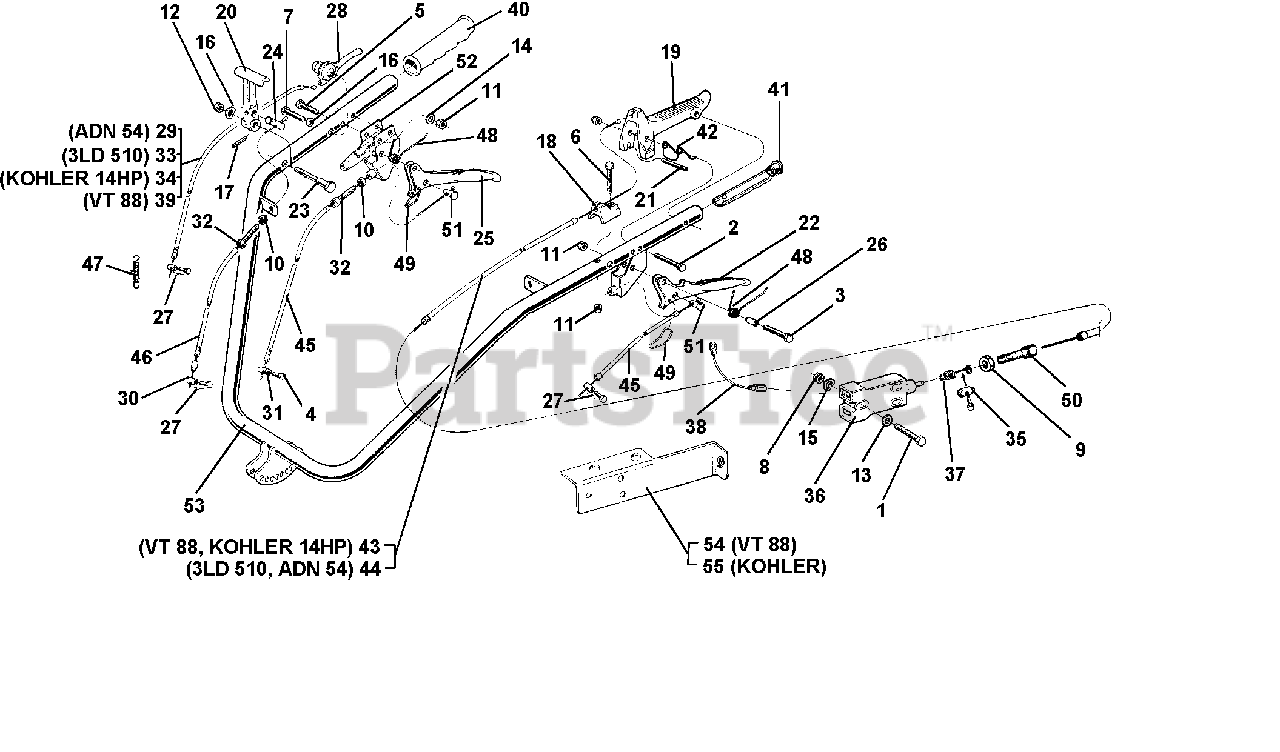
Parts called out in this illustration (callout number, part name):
1	SCREW TE M4 X 25
2	SCREW TE M6 X 45
3	SCREW M6 X 25
4	SCREW TE M6 X 16
5	SCREW M6 X 40
6	SCREW M6 X 35
7	SCREW TE M8 X 40
11	NUT, SELF LOCKING M6
12	NUT, SELF LOCKING M8
13	FLAT WASHER 4.3
14	WASHER, LOCK 6.4
15	LOCK WASHER B 4.3
16	WASHER, LOCK 8.4
17	PIN, LOCKING 4 X 20
18	SHEATH STOP OF MOTOR STOP
19	MOTOR STOP LEVER
20	LEVER DIFFERENTIAL LOCKING
21	LEVER STOP FOR MOTOR STOP
22	CLUTCH LEVER
24	DRILLED PIN
26	LEVER SPACER
27	CLAMP, CABLE
28	LEVER, ACCELERATOR
29	GAS WIRE AND SHEATH
30	END, SHEATH
31	PIN, CABLE CLAMP
32	SCREW, ADJUSTING M8
33	GAS WIRE AND SHEATH
34	CABLE & SHEATH, ACCEL. L 1680
35	CABLE CLAMP
36	STOP SWITCH
37	SWITCH SPRING
38	SWITCH CABLES
39	WIRE, SHEATH 1850 GAS
42	MOTOR STOP LEVER SPRING
43	MOTOR STOP WIRE AND SHEATH
44	SHEATH CABLE
45	SHEATH CABLE
46	SHEATH CABLE
47	KOHLER GAS CONTROL
48	LEVER SPRING
50	ADJUSTING SCREW
52	COUPLING FOR DOUBLE LEVER
55	KOHLER STOP SWITCH SUPPORT
